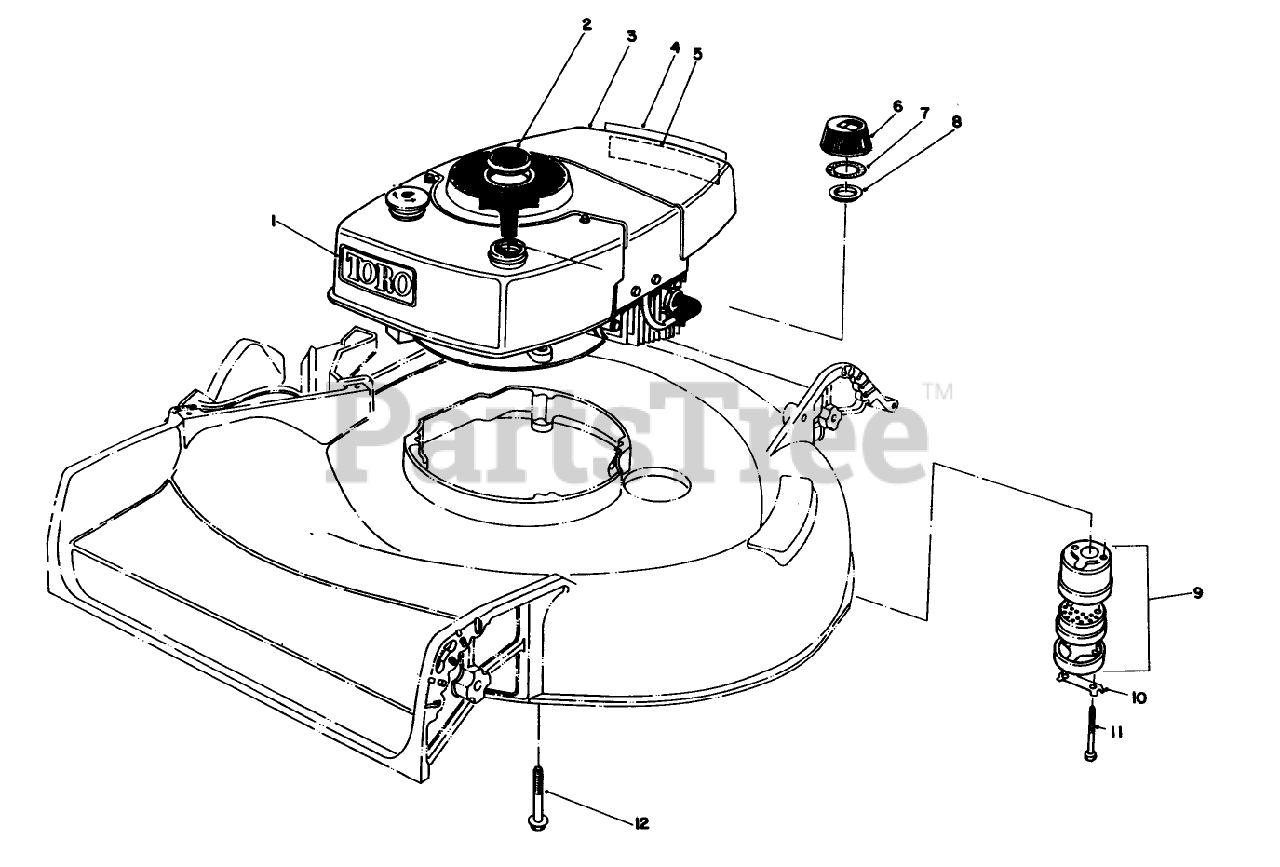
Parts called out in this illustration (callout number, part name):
3	Engine
7	GASKET
9	MUFFLER ASM
10	CLIP - LOCKING
11	SCREW-HH
12	3/8-16 X 2-3/4 CAPSCR
